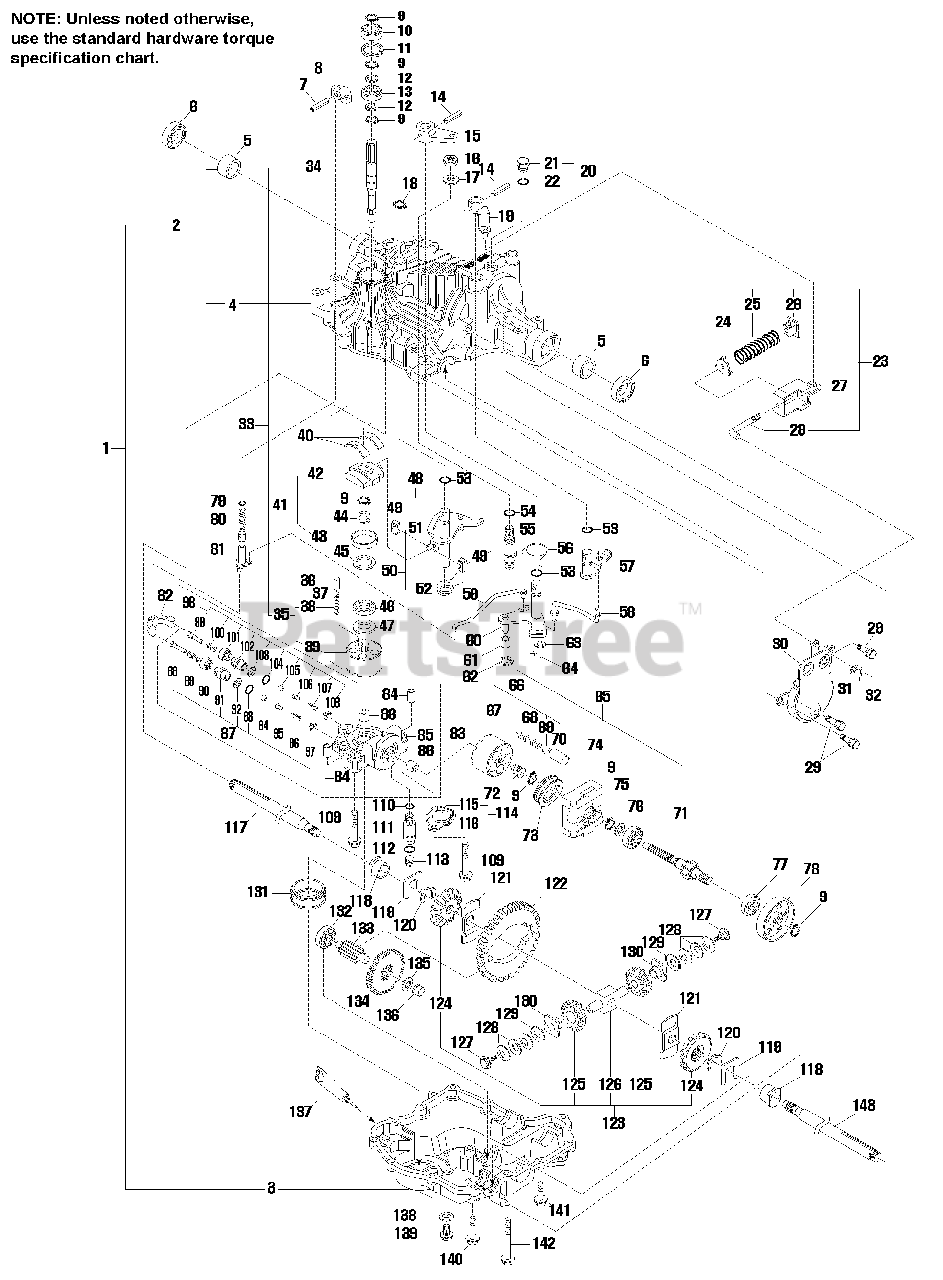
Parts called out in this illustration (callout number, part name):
1	Transaxle Case Set
2	Upper Case, Complete with Bushings
4	Upper Case
6	Seal (S25.4x42x8)
7	Pin 4.0Ax25
8	Arm (Valve Release)
10	Seal TC153507
13	Bearing 6202C3
14	Pin 6.0Ax40
15	Arm (Brake)
19	Arm B (Brake)
20	Plug 9/16, Complete
22	O-RING
23	Brake Rod, Complete
24	Spring Guide
25	SPRING
26	Adjuster Complete
27	Holder (Spring)
28	Rod (Adjuster)
29	Bolt w/Washer 8x20
30	Band Brake (Interlock)
33	Pump Shaft Set
35	Cylinder Block, Complete
36	PISTON
38	SPRING (Piston)
39	Cylinder Block
40	Thrust Metal
41	Swash Plate, Complete
42	Swash Plate
43	Swash Plate Bushing
45	Thrust Plate (B)
46	Bearing K81106
47	Thrust Plate (A)
49	Block (Shift)
50	Control Shaft, Complete
51	Control Shaft
52	SPRING (Torsion)
53	Packing P 12
54	O-RING, 1A P10A
55	Fulcrum (Eccentric)
56	Return Sp (Brake)
57	Arm A (Brake)
58	Rod (Brake)
59	Rod (Bypass)
60	Shaft (Brake)
65	Motor Shaft Set
66	Cylinder Block, Complete
67	Cylinder Block
68	SPRING (Piston)
70	PISTON
73	Bearing (Thrust)
76	Bearing 6202C3
77	Seal TC173507
78	Brake Drum
79	Packing P 7
81	Shaft (Bypass)
83	Center Case, Complete
84	Knock Pin 12x22
85	Center Case
86	Bearing 12x12
87	Valve (A-1 set)
88	Push Pin
89	SPRING
90	Body (B Bypass)
92	Back-Up Ring
93	Packing 1015
95	Holder (Ball)
96	SPRING
97	Holder (Bypass)
98	Valve (A-2 set)
99	Push Pin
100	SPRING
101	Body (B Bypass)
103	Back-Up Ring
104	Packing 1015
106	Holder (Ball)
107	SPRING
108	Holder (Bypass)
109	Bolt 10x60
110	Packing P 11
112	Packing P 14
114	Magnet, Complete
116	Holder, Magnet
117	Axle Shaft R
119	Thrust Washer
121	Thrust Washer (Diff.)
122	Final Gear 55
123	Diff. Gear Kit
124	Diff. Side Gear
125	Diff. Pinion
126	Shaft (Diff. Pinion)
127	Bolt
128	Disk Spring
130	Taper Bush
132	Bearing 6203
133	Shaft (Final Pinion)
134	Gear 51 (Final Shaft)
137	Sealant
138	Washer, Seal 8
140	Tapping, Screw 8x40
141	Tapping, Screw 8x30
143	Axle Shaft L
